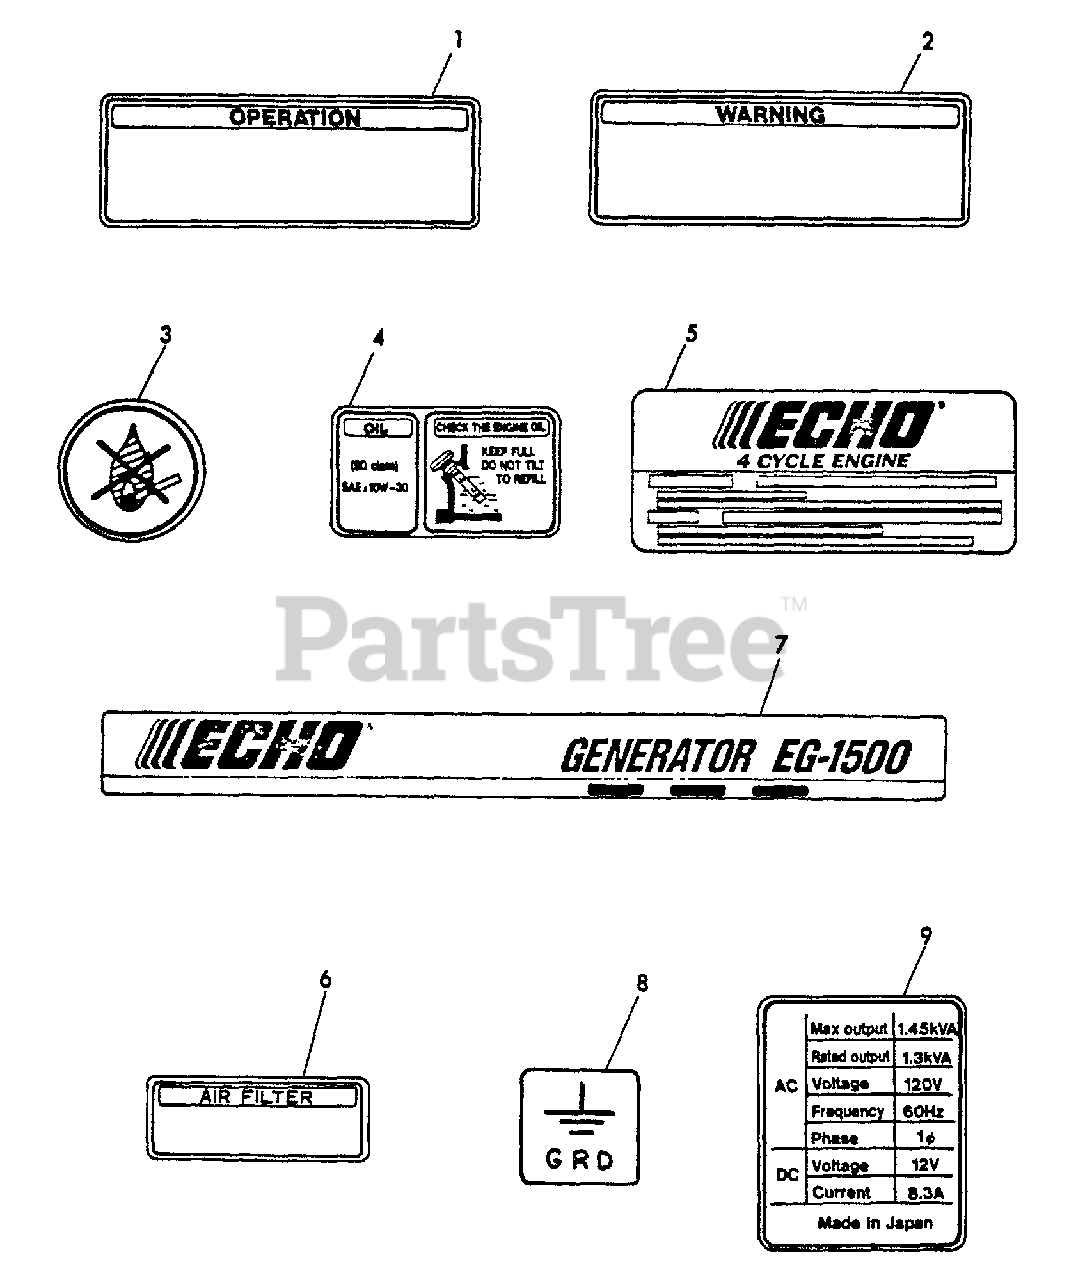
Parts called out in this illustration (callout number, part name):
1	LABEL
2	LABEL - WARNING
3	LABEL, NON FIRE
4	LABEL, OIL
5	LABEL - ECHO
6	LABEL - AIR FILTER
7	LABEL - MODEL EG1500
8	LABEL, EARTH
9	LABEL - GENERATOR
